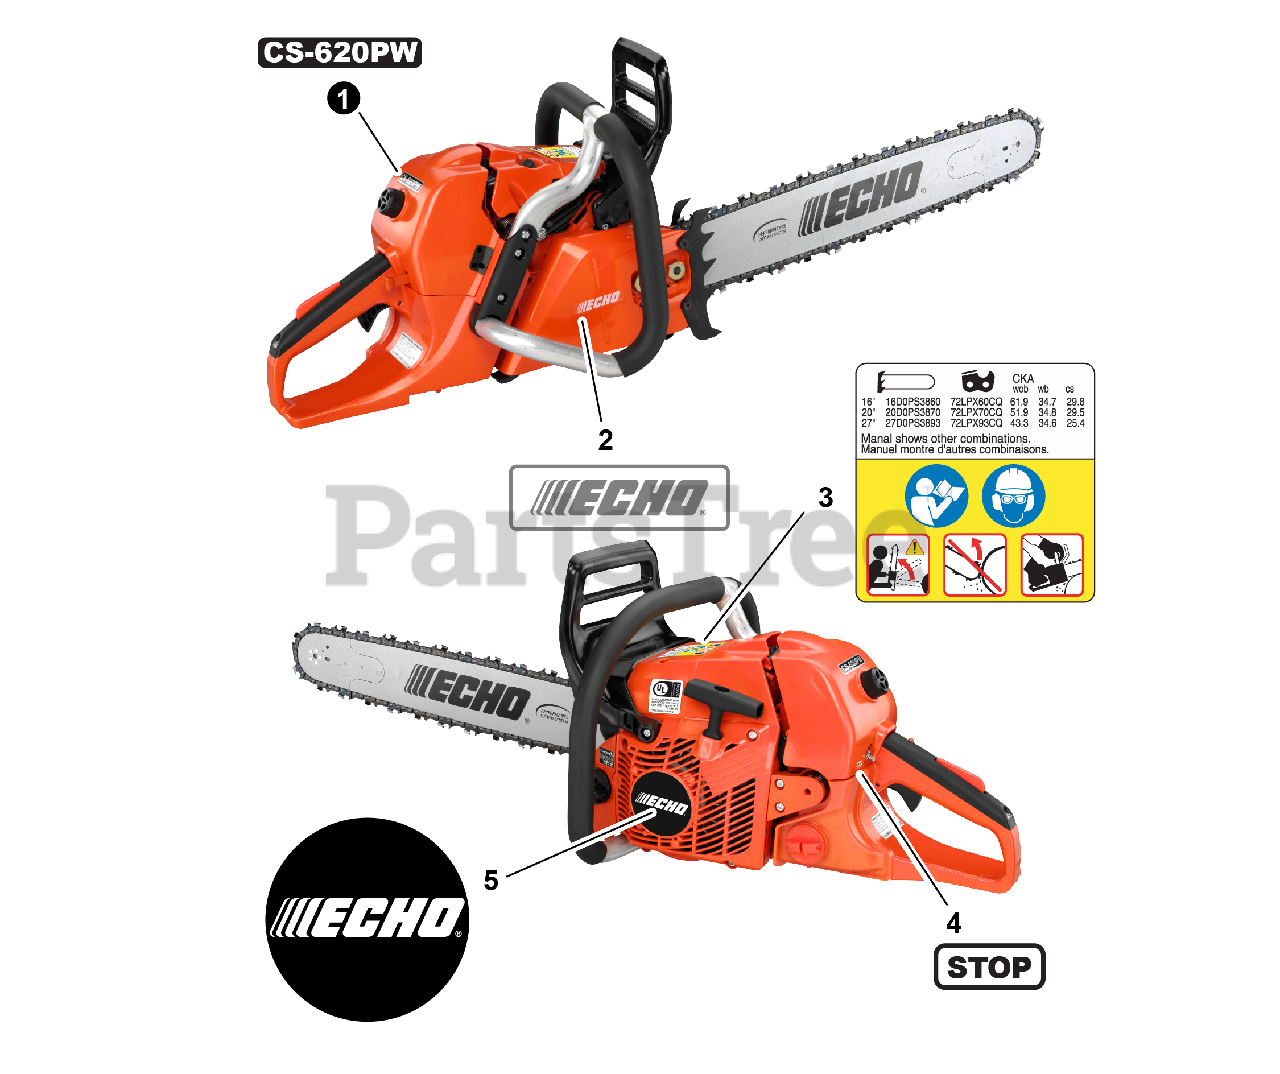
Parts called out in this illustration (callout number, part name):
1	LABEL, MODEL CS-620PW
2	LABEL, ECHO
3	LABEL, CAUTION
4	LABEL, STOP
5	LABEL, RECOIL STARTER
